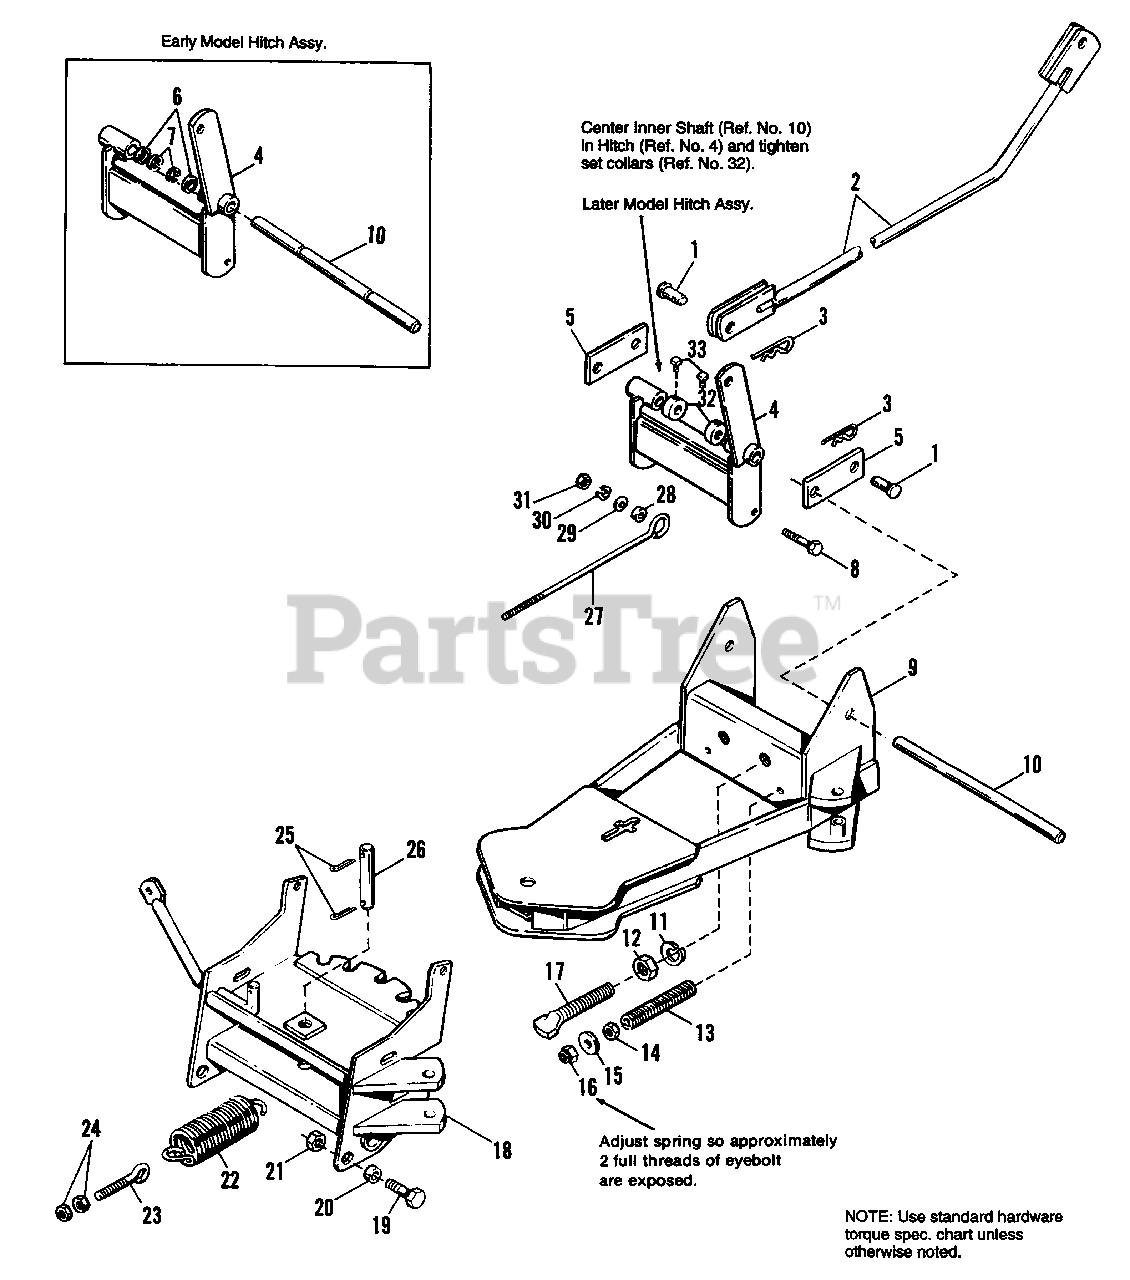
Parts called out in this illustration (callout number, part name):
1	PIN, Clevis
2	ROD ASSY., Lift
3	CLIP, Spring
4	HITCH ASSY.
6	WASHER, Plain, 41/64 x 1-1/4 x 1/16
7	E-RING, Retaining
8	CAPSCREW, Hex Hd., 5/8-11 x 2" Lg.
9	HITCH ASSY, Dozer
10	SHAFT, Inner
11	LOCKWASHER, 3/4"
12	NUT, Hex, 3/4-10
13	SPING, Compression
14	NUT, Hex Jam, 3/8-16
15	WASHER, 13/32 x 1-1/4 x 1/4
16	NUT, Hex, 3/8-16
17	STUD, 3/4-10
18	FRAME ASSY, Pivot
19	CAPSCREW, Hex Hd., 1/2-13 x 1 Lg.
21	NUT, Hex, Lock, 1/2-13
22	SPRING, Tension
24	NUT, Hex, 5/16-18
25	PIN, Cotter, 3/16 x 1-1/4 Lg.
29	WASHER, Plain, 41/64 x 1-3/4 x 1/8
30	LOCKWASHER, 5/8
31	NUT, Hex, 5/8-11
32	SET COLLAR
33	SETSCREW, Square Hd. Cup Point, 5/16-18 x 1/2
